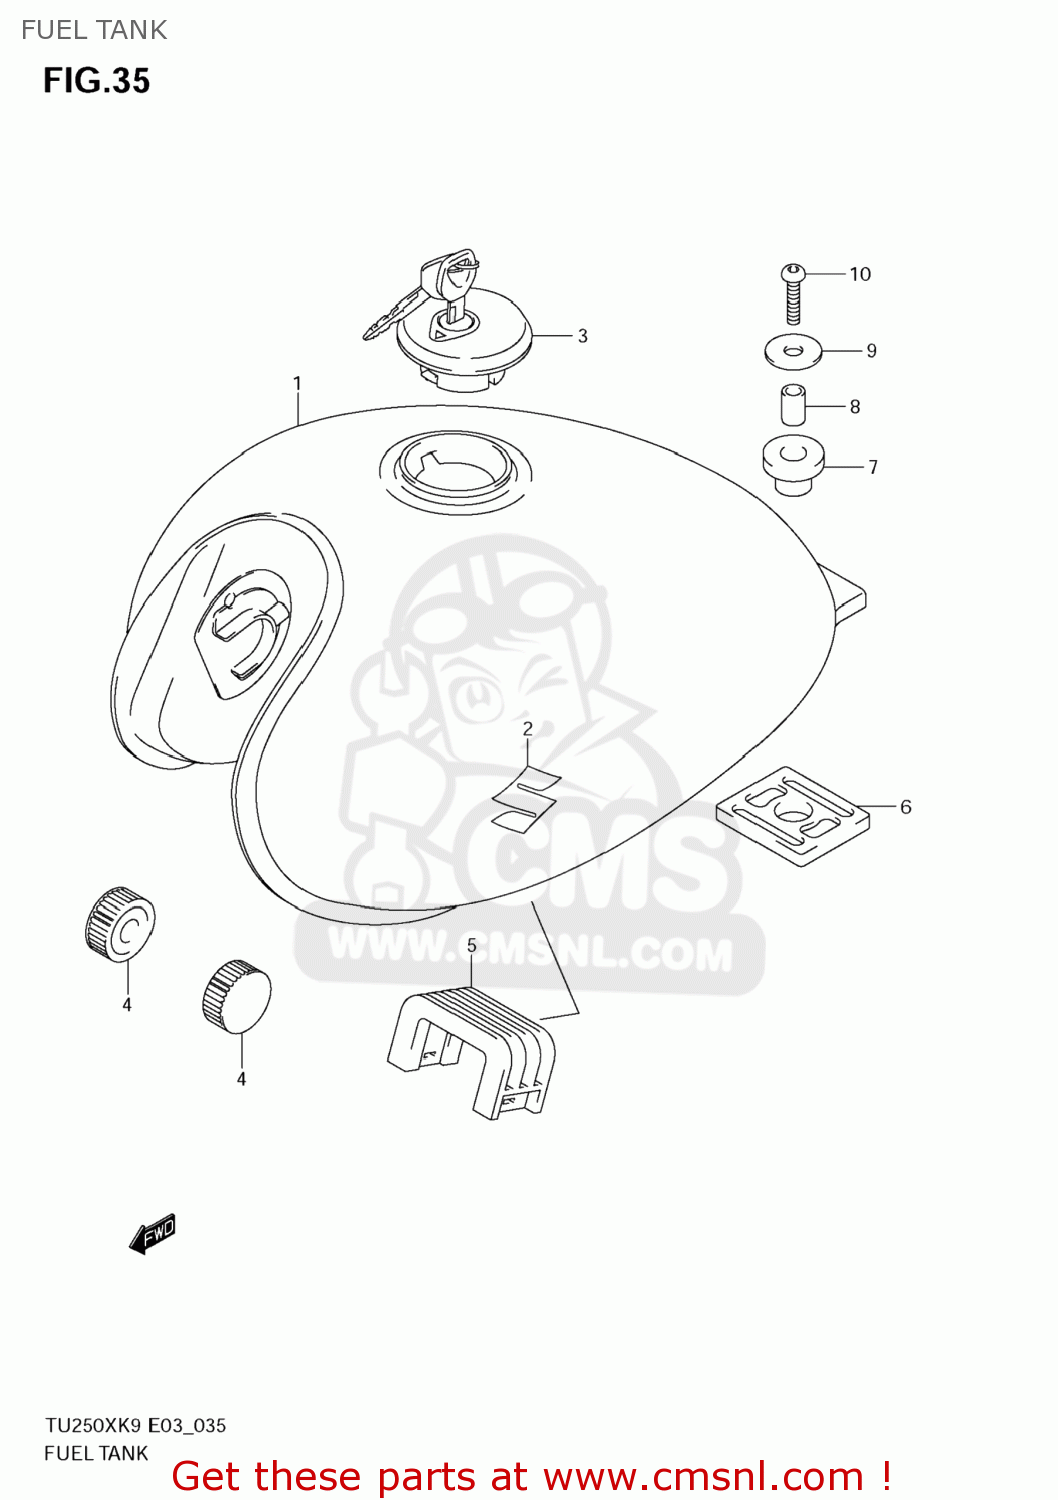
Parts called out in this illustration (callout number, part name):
1	TANK ASSY,FUEL(RED)
2	EMBLEM,S
3	CAP SET,FUEL TANK
4	CUSHION
5	CUSHION,TANK UPR FR
6	CUSHION,FUEL TANK RR LWR
7	CUSHION,FUEL TANK RR UPR
8	SPACER (8.2X12.5X23.5)
9	WASHER(8.5X33X1.5)
10	BOLT
